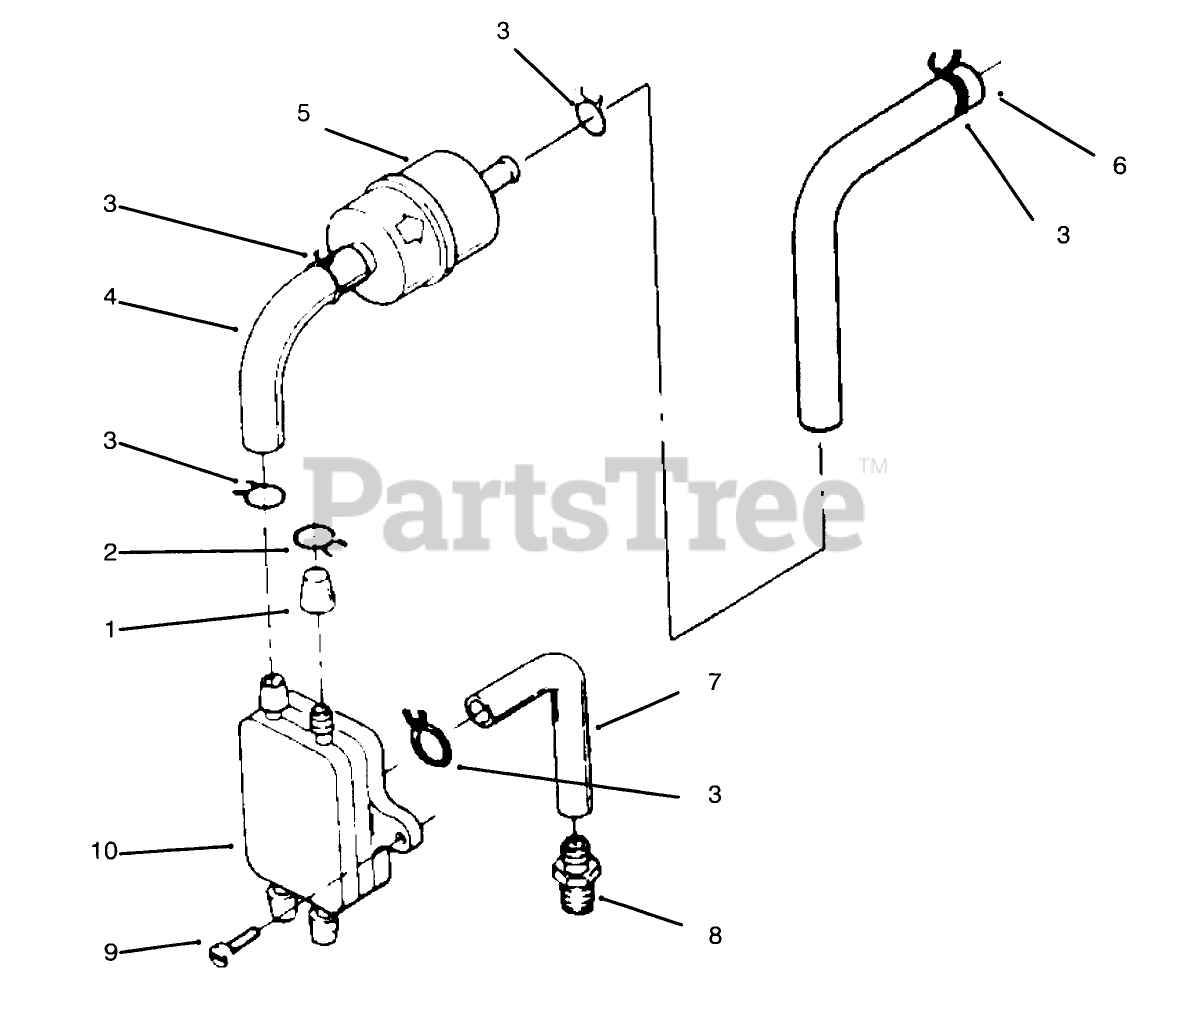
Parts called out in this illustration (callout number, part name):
1	CAP-FUEL OUTLET
2	CLAMP
3	CLAMP-HOSE
5	FILTER-FUEL
6	HOSE - FUEL
7	HOSE-VACUUM
8	FITTING-BARB
9	Screw
10	Pump-Fuel (Incl. Ref. #1 & 2)
